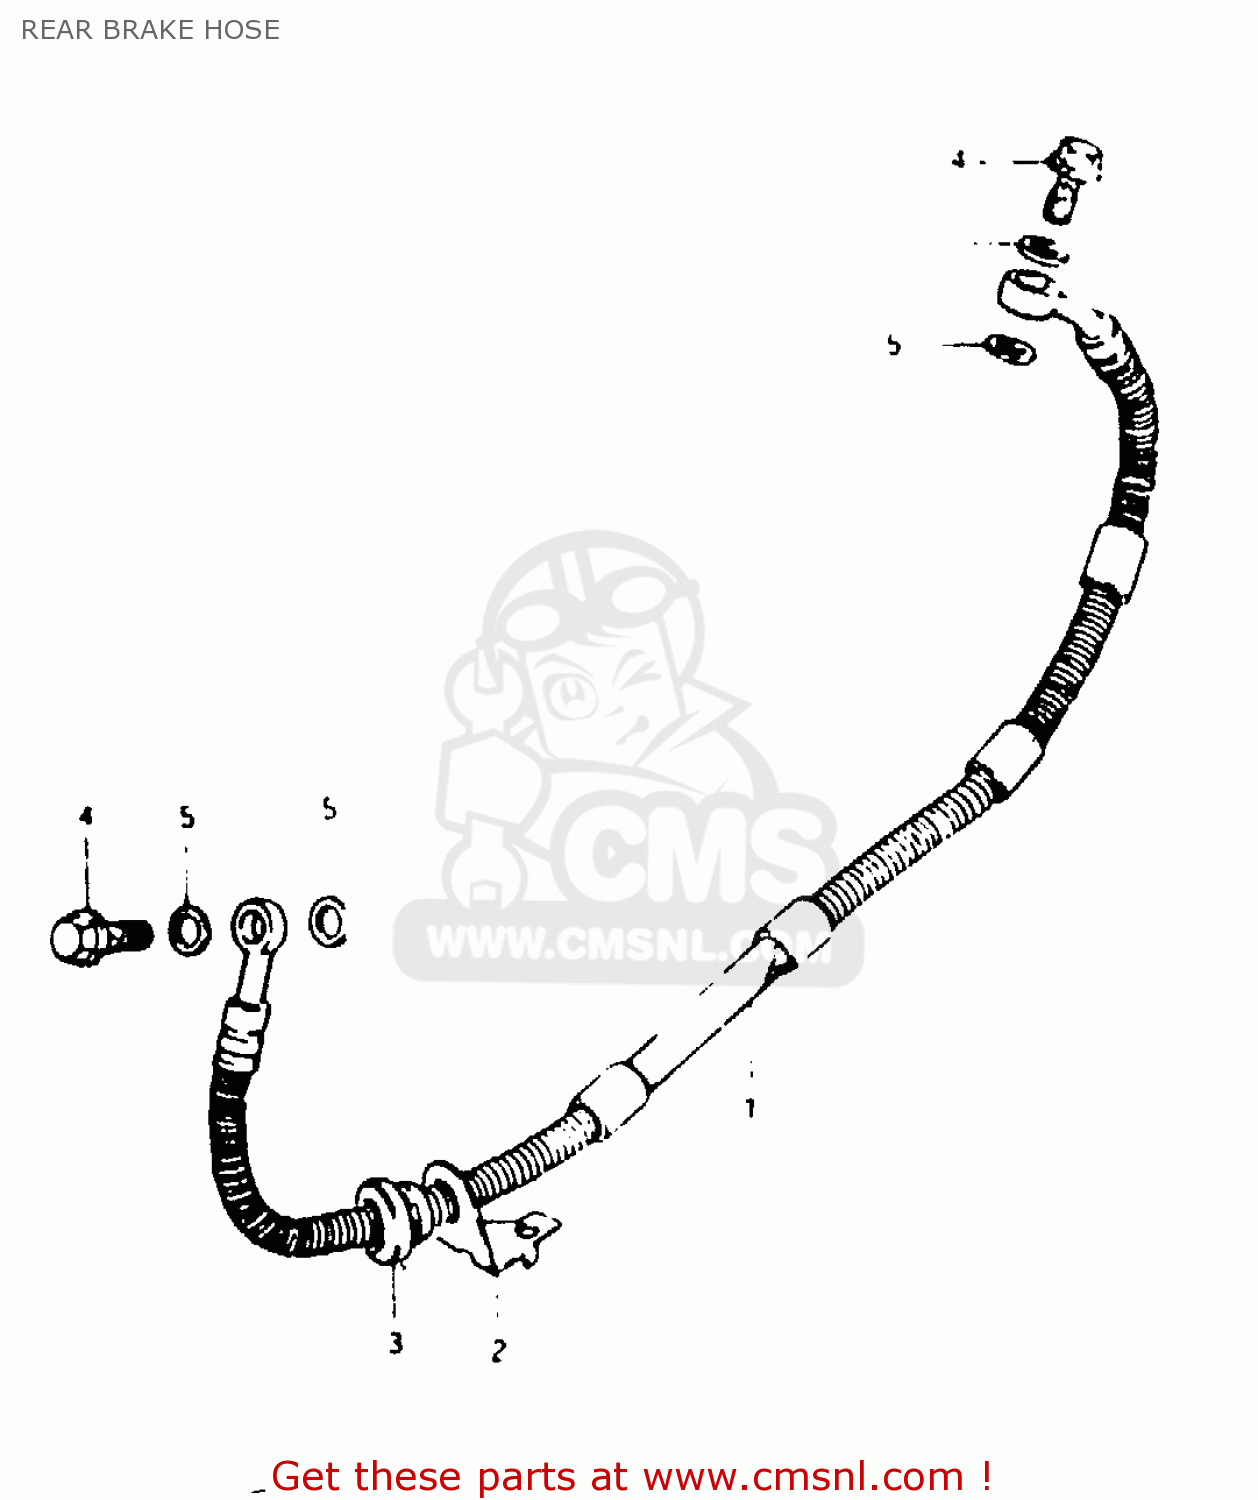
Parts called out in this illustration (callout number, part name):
1	HOSE, REAR BRAKE
2	GUIDE,BRAKE HOSE
3	GROMMET,BRAKE HOSE GUIDE
4	BOLT,UNION
5	WASHER
